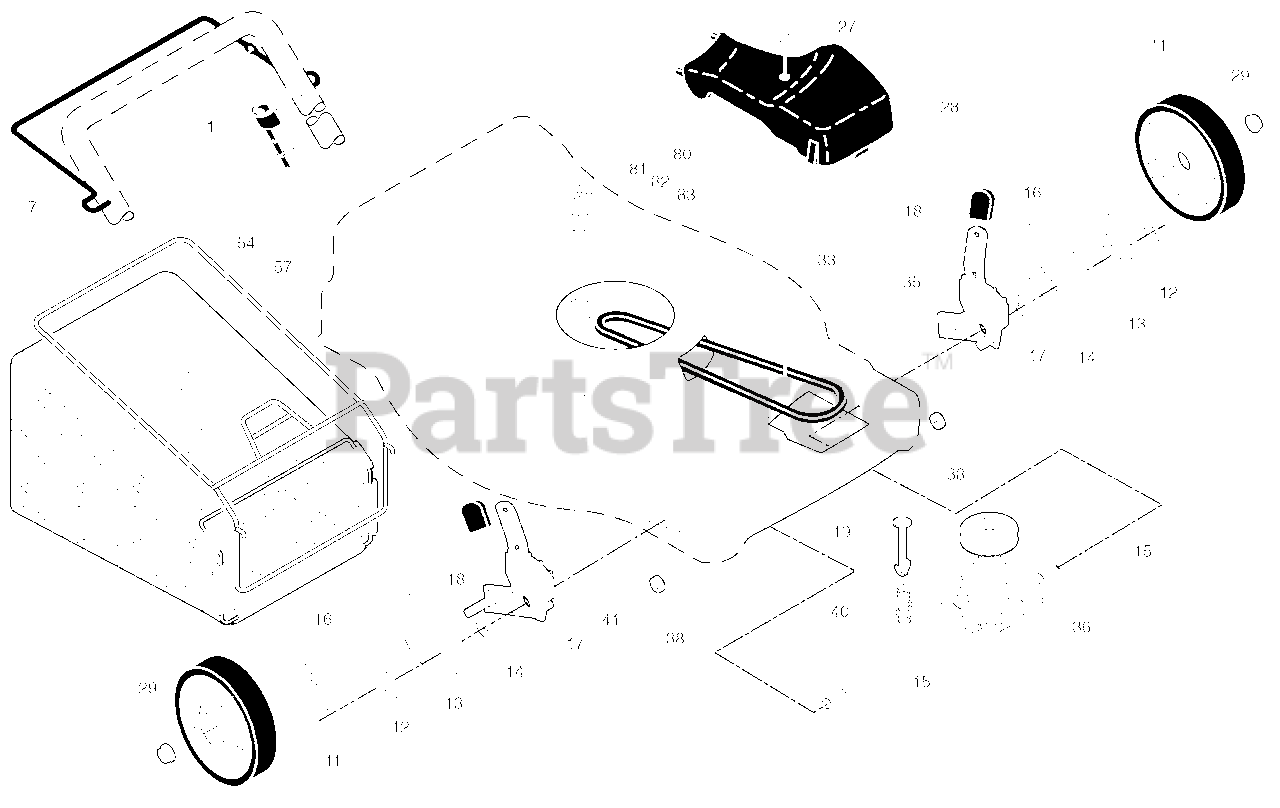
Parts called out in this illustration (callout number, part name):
1	Drive Control Assembly
7	Bar, Drive Control
11	Wheel & Tire Assembly, Front
12	E-Ring
13	Pinion
14	Dust Cover
15	Pawl, Drive
16	Washer, Flat 3/8
17	Bearing, Wheel Adjuster
18	Selector Knob
19	Retainer, Spring
27	Pan Head Tapping Screw #10-24 x 2-3/4
28	Drive Cover
29	Locknut, Hex
35	Kit, Wheel Adjuster, LH
36	Gear Case Assembly, Complete
38	Locknut 1/4-20
40	Spring
41	Kit, Wheel Adjuster, RH
54	Grassbag Assembly
57	Frame, Grassbag
80	Water Washout Assembly
81	Fitting, Hose, Water Washout
82	Washer, Lock, Internal Tooth
83	Locknut, Hex, with O-Ring
